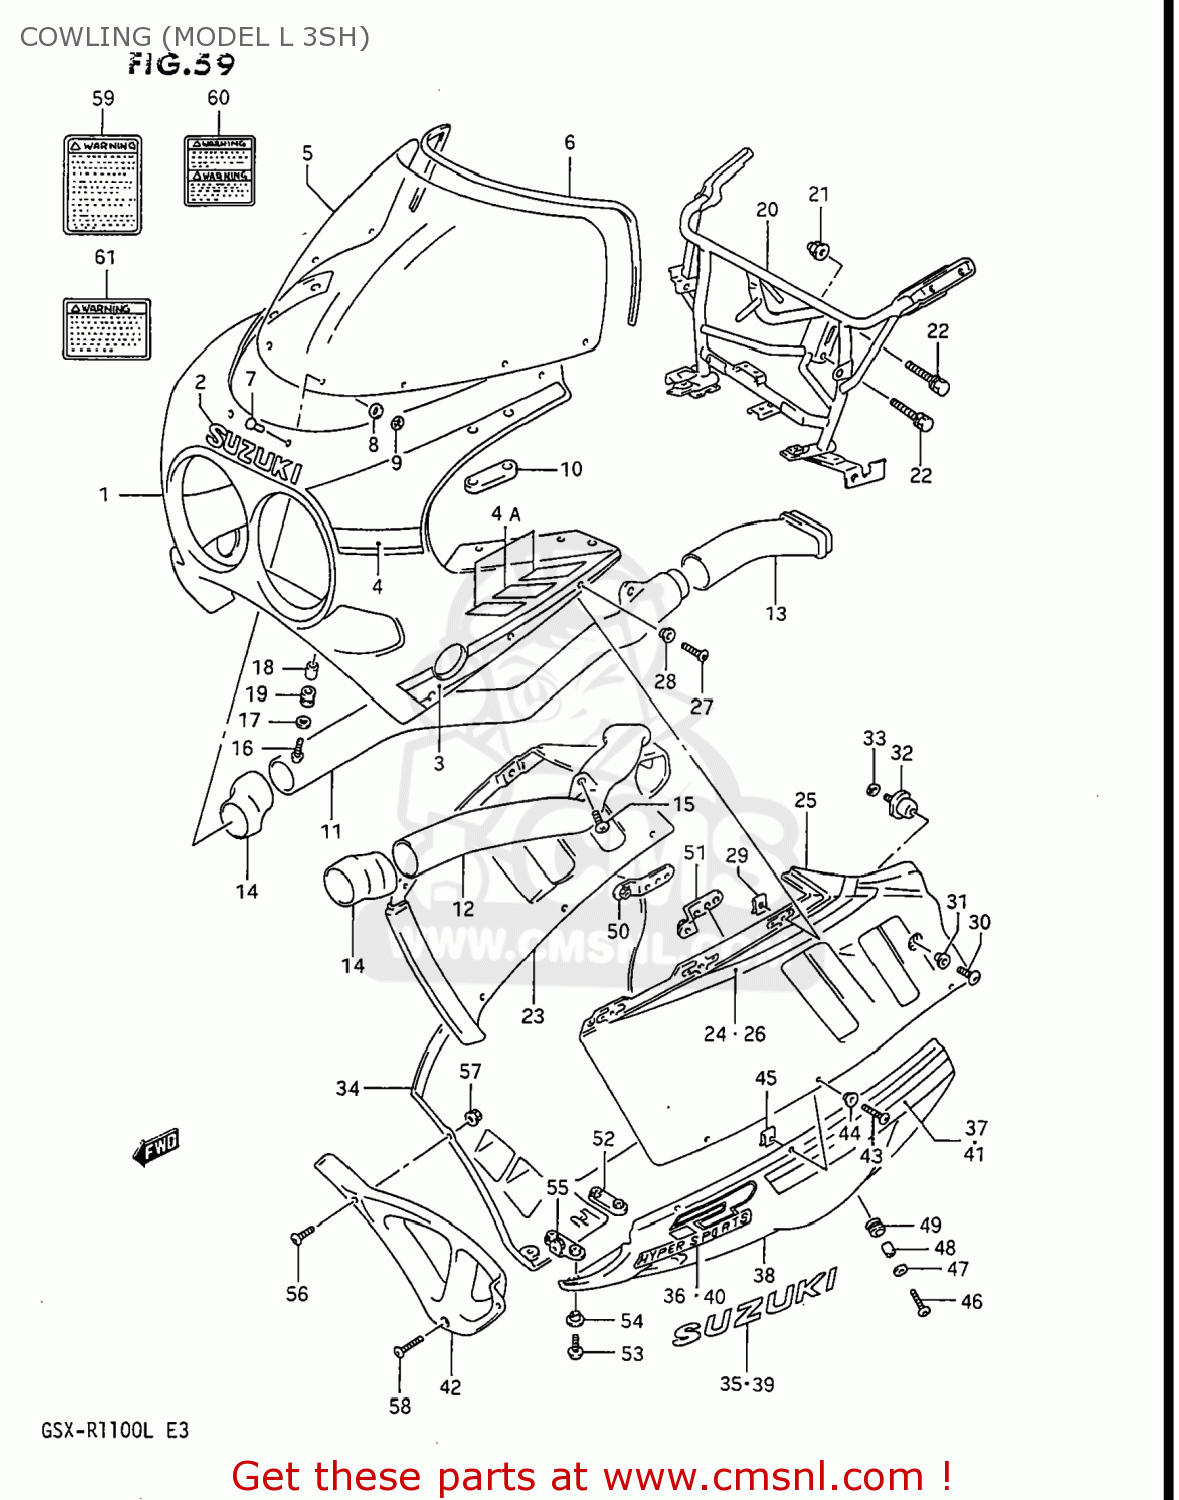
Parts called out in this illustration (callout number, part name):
1	BODY ASSY,COWLING
2	EMBLEM,COWLING UPR
3	TAPE SET,COWLING,UPPER SIDE
4	TAPE SET,COWLING,UPPER,FRONT
4A	TAPE SET,COWL
5	SCREEN,WIND
6	MOLDING
7	PIN,WINDSCREEN
8	CUSHION
9	NUT
10	CUSHION,RR VIEW MIRRORR
11	PIPE,AIR INTAKE FR,R
12	PIPE,AIR INTAKE,FRONT
13	PIPE,AIR INTAKE RR,R
14	JOINT,AIR INTAKE
15	SCREW, CENTER
16	SCREW(6X20)
17	WASHER(6.5X18X1)
18	SPACER
19	CUSHION
20	BRACE,COWLING
21	NUT ,8MM
22	BOLT
23	COVER,COWLING SIDE,RIGHT
24	TAPE,COWL SIDE,R
25	COVER,COWLING SIDE,LEFT
26	TAPE,COWL SIDE,L
27	SCREW(5X18)
28	WASHER(5.2X14X1.5)
29	NUT,HEADLAMP HOUSING,UPPER
30	SCREW(6X12)
31	WASHER(6.3X16X1.5)
32	CUSHION,COWLING
33	WASHER,LOCK
34	COWLING,UNDER,RIGHT
35	EMBLEM
36	EMBLEM,COWLING,UNDER
37	TAPE,COWLING,UNDER STRIPE
38	COWLING,UNDER,LEFT
39	EMBLEM,COWLING UNDER,L
40	EMBLEM,COWLING,UNDER
41	TAPE,COWLING,UNDER STRIPE
42	COWLING,UNDER,CENTER
43	SCREW(5X18)
44	WASHER(5.2X14X1.5)
45	NUT,HEADLAMP HOUSING,UPPER
46	SCREW(6X20)
47	WASHER(6.5X18X1)
48	SPACER
49	CUSHION
50	BRACKET
51	BRACE,COWLING UNDER,LH
52	BRACE,COWLING LWR COVER RR
53	SCREW(6X16)
54	WASHER(6.3X16X1.5)
55	BRACE,COWLING LWR COVER
56	SCREW(5X14)
57	NUT
58	SCREW(6X16)
59	LABEL (WARNING SCREEN)
60	LABEL (WARNING)
61	LABEL
